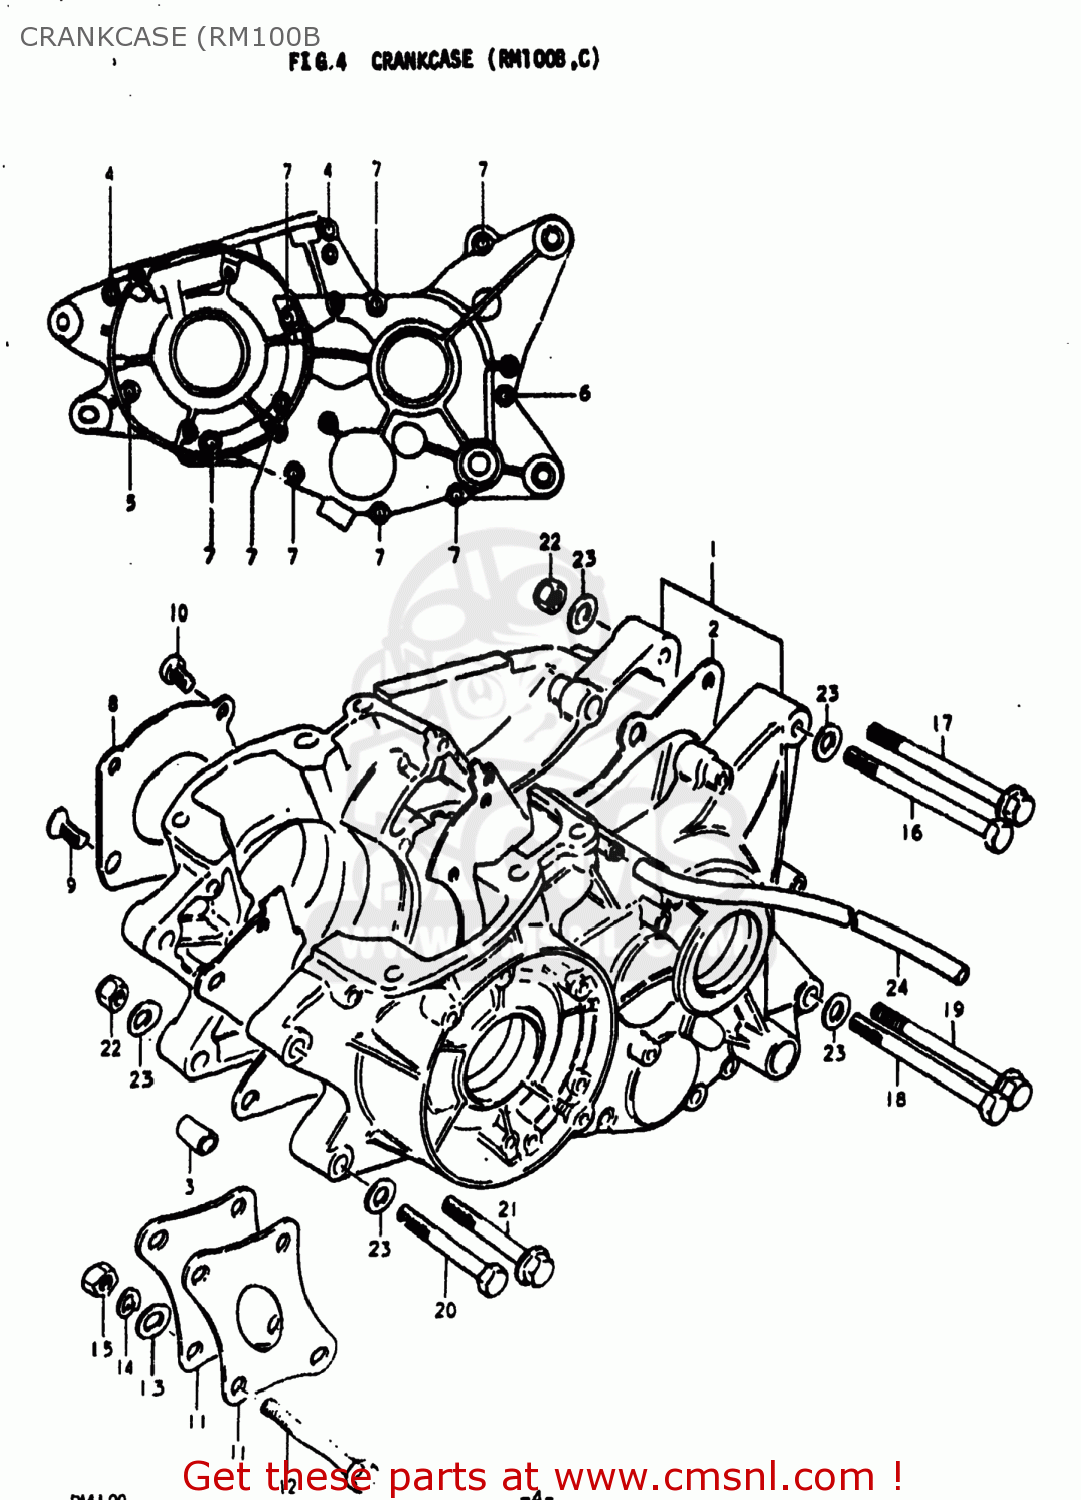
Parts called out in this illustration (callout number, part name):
1	CRANKCASE SET
2	GASKET,CRANKCASE (MCA)
3	PIN
4	SCREW (6X35)
5	SCREW (6X45)
6	SCREW
7	SCREW 6X60
8	PLATE,OIL RESERVOIR
9	SCREW
10	SCREW 6X12
11	PLATE,ENGINE MOUNTING
12	BOLT
13	WASHER
14	LOCK WASHER
15	NUT
16	BOLT 8X105
17	BOLT
18	BOLT 8X100
19	BOLT
20	BOLT
21	BOLT (8X70)
22	NUT
23	WASHER
24	HOSE
